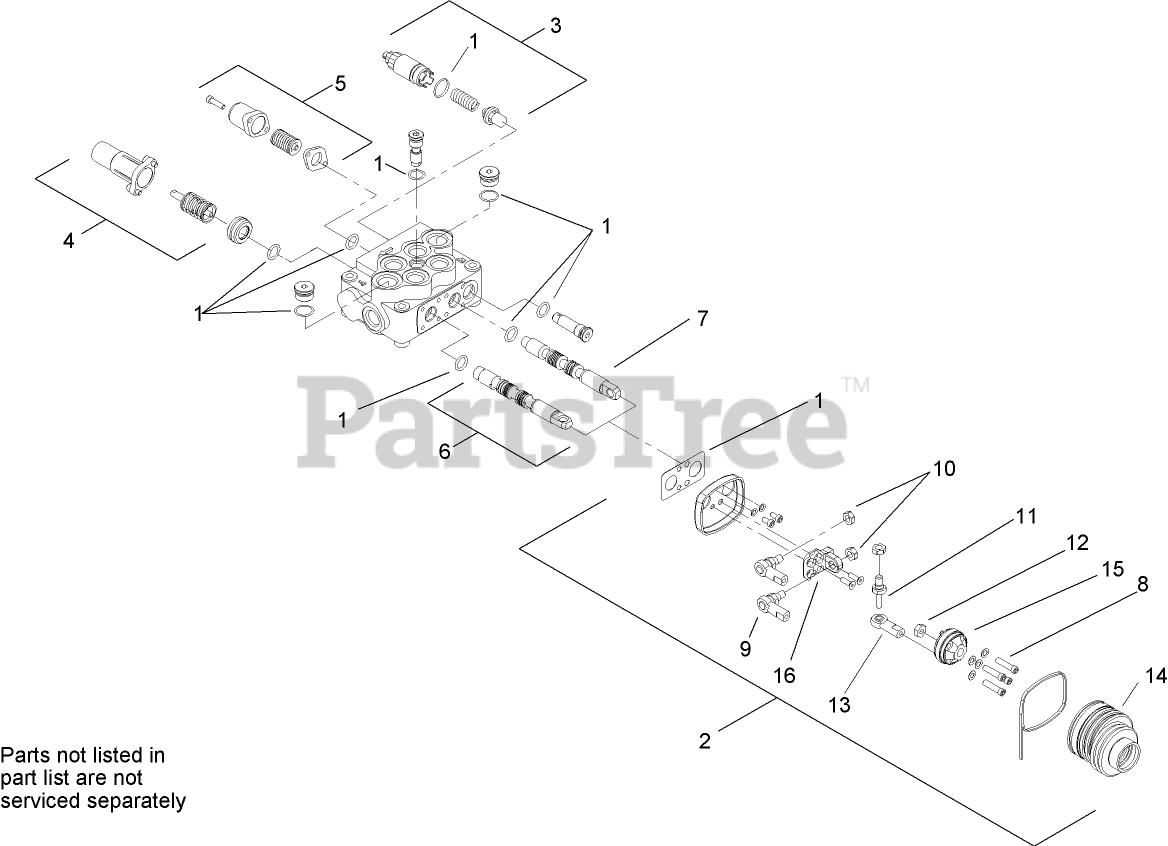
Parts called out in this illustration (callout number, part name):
1	SEAL KIT
2	JOYSTICK KIT
3	VALVE-RELIEF
4	Kit-Spring, Valve
5	Kit-Spring
8	Screw-Joystick
9	Joint-Articulated
10	Nut-Joystick
11	Pin-Joystick
12	NUT-GALVANISED
13	End-Rod
14	BOOT-RUBBER
15	HOLDER-ARTICULATED
16	PIVOT-VALVE
